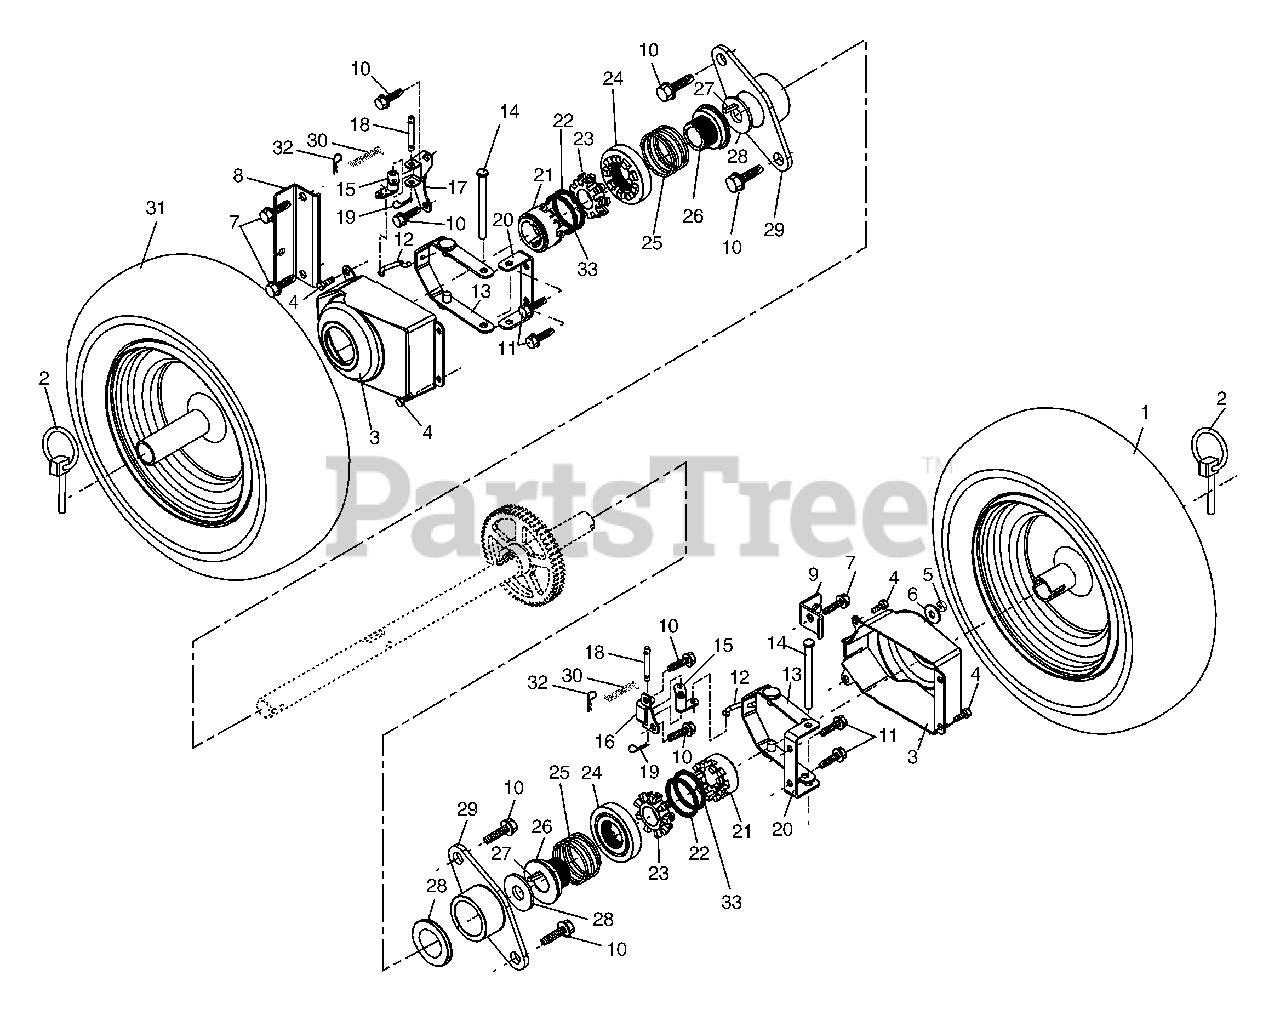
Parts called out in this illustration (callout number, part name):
1	Wheel Assembly, 16", with Power Steering, LH
2	Pin, Klik 1/4
3	Cover, Power Steering
4	Screw, Hex Head #10-24 x 1/2
5	Nut, Lock 5/16-18
6	Washer, Flat 5/16
7	Screw, Hex Head 3/8-16 x 1
8	Bracket, Steering Cable, RH
9	Bracket, Steering Cable, LH
10	Screw, Hex Head 5/16-18 x 3/4
11	Screw, Hex Head 5/16-18 x 1/2
12	Link, Steering Lever
13	Lever Assembly, Steering
14	Pin, Steering Lever
15	Bellcrank Assembly
16	Bracket Assembly, LH Steering
17	Bracket Assembly, RH Steering
18	Pin, Steering Bellcrank
19	Retainer, Hairpin
20	Bracket, Lever Assembly
21	Driver, Wheel
22	Ring, Wire Retainer
23	Lobe, Wheel
24	Slide, Clutch
25	Spring, Clutch Slide
26	Lobe, Axle
27	Key, Square 1/4 x .875
28	Washer, Thrust (1")
29	Bearing, Axle
30	Spring, Return, Steering Latch
31	Wheel Assembly, 16", with Power Steering, RH
32	Clip, Retainer
33	Ring, Retaining
